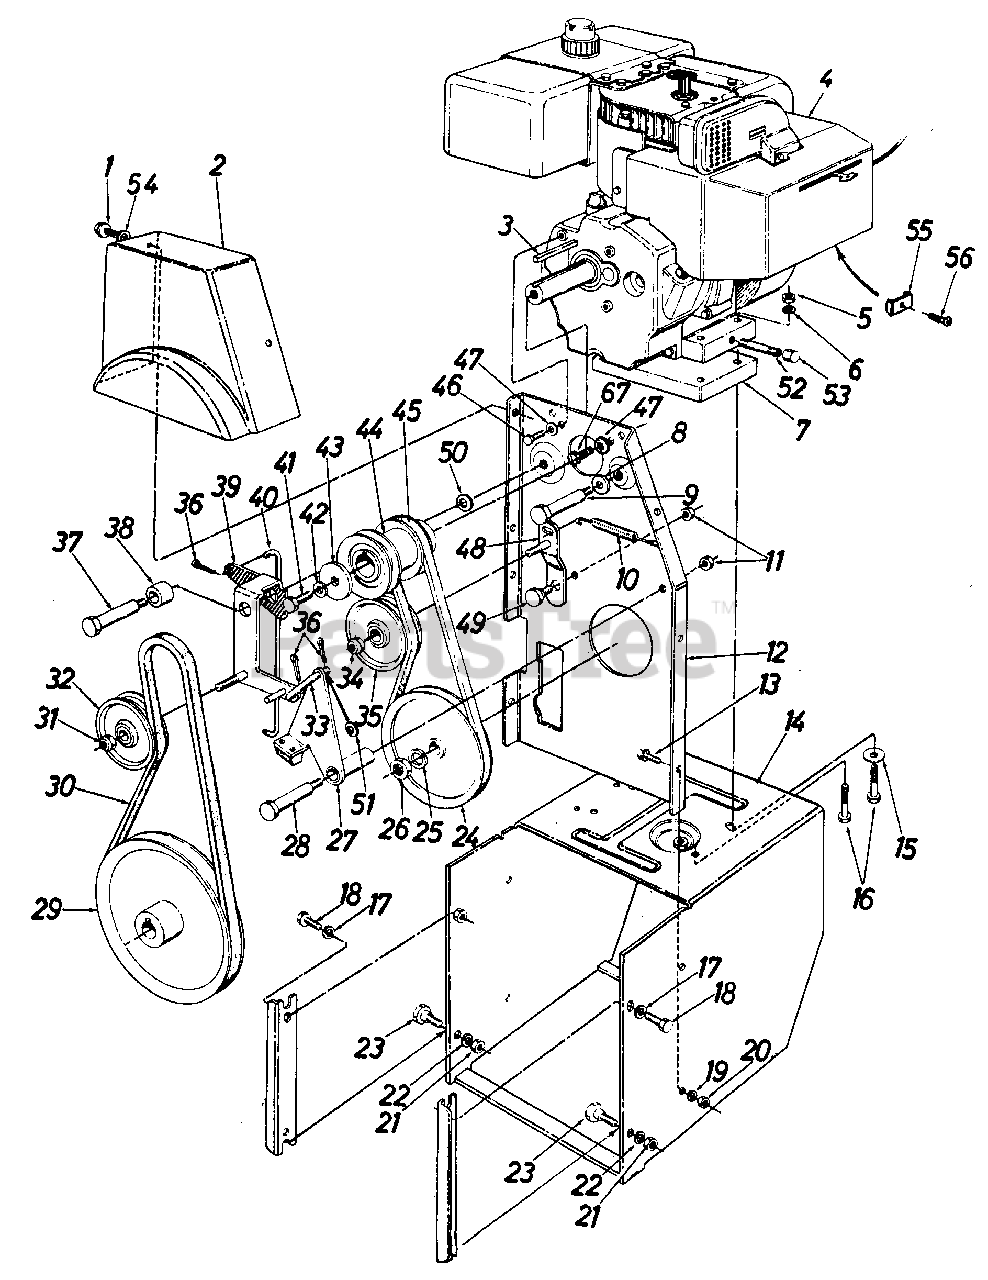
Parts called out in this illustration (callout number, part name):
1	Hex Wash. Self-Tap Scr. 5/16-24 x .50" Lg.
2	Belt Cover
3	Sq. Key 1/4" X 1.50" Lg.
4	Engine
5	Hex Nut 5/16-18 Thd.*
6	L-Wash. 5/16" Scr.*
7	Engine Spacer Ass'y.
8	Bell-Wash. .40 I.D. x .88 O.D.
9	Shld. Scr 498" Dia. x 3.00" Lg.
10	Ext. Spring .38 O.D. x 3.18" Lg.
11	Hex Cent. L-Nut 3/8-16 Thd.
12	Engine Brkt. Ass'y.
13	Hex Sems Scr. 5/16-18 x .75" Lg.*
14	Frame Ass'y.
15	Fl-Wash. .345 I.D. x .75 O.D. x .060
16	Hex Scr. 5/16-18 x 2.50" Lg.*
17	L-Wash. 3/8" Scr. H.D.
18	Pilot Scr. 3/8-16 x .88" Lg.
19	L-Wash. 5/16" Scr.*
20	Hex Nut 5/16-18 Thd.*
21	Hex Nut 3/8-16 Thd.*
22	L-Wash. 3/8" Scr. H.D.
23	Shld. Scr. .498" Dia. x .340" Lg.
24	V-Puiley .628 I.D. x 7.50 O.D.
25	L-Wash. for 5/8" Scr.*
26	Hex Ins. Jam L-Nut 5/8-18 Thd.
27	Brake Brkt. Ass'y.
28	Shld. Scr. .498" Dia. x 2.00" Lg.
29	V-Puiley .875 I.D. x 10.12 O.D.
30	V-Belt 1/2" X 45.0" Lg.
31	Hex Ins. Jam L-Nut 3/8-24 Thd.
32	Fl-ldler w/ Flanges 3.0 O.D.
33	Brake Linkage Ass'y.
34	Hex Ins. Jam L-Nut 3/8-24 Thd.
35	3.0" O.D. Fl-ldler w/ Flanges
36	Int. Cot. Pin 5/16" Dia.
37	Shld. Scr. .625 Dia. x 2.750" Lg.
38	Spacer .75 O.D. x 1.00" Lg.
41	Hex Bolt 3/8-24 x 1.25" Lg.
42	L-Wash. 3/8" Scr. H.D.
43	Fl-Wash.
44	Engine Pulley-Double Groove
45	V-Belt 3/8 x 35.5 Lg.
46	Hex Scr. 5/16-24 x .62" Lg.
47	Bell-Wash. .345 I.D. x .88 O.D. x .060
48	Drive Idler Brkt. Ass'y.
49	Shld. Scr.-.625" Dia. x .170 " Lg .
50	Bell-Wash. .40 I.D. x 1.12 O.D.
51	Fl-Wash. .34 I.D. x .750 O.D. x .05
52	Pipe Nipple-1/2" Pipe Thd. x 3.00" Lg.
53	Hex Scr. 1/4-18 Pipe Thd.
54	Fl-Wash. .340 I.D. x .62 O.D. x .62
55	Throttle Control Wire Clamp
56	Hex Sems Scr. #10-32 x .62" Lg.
